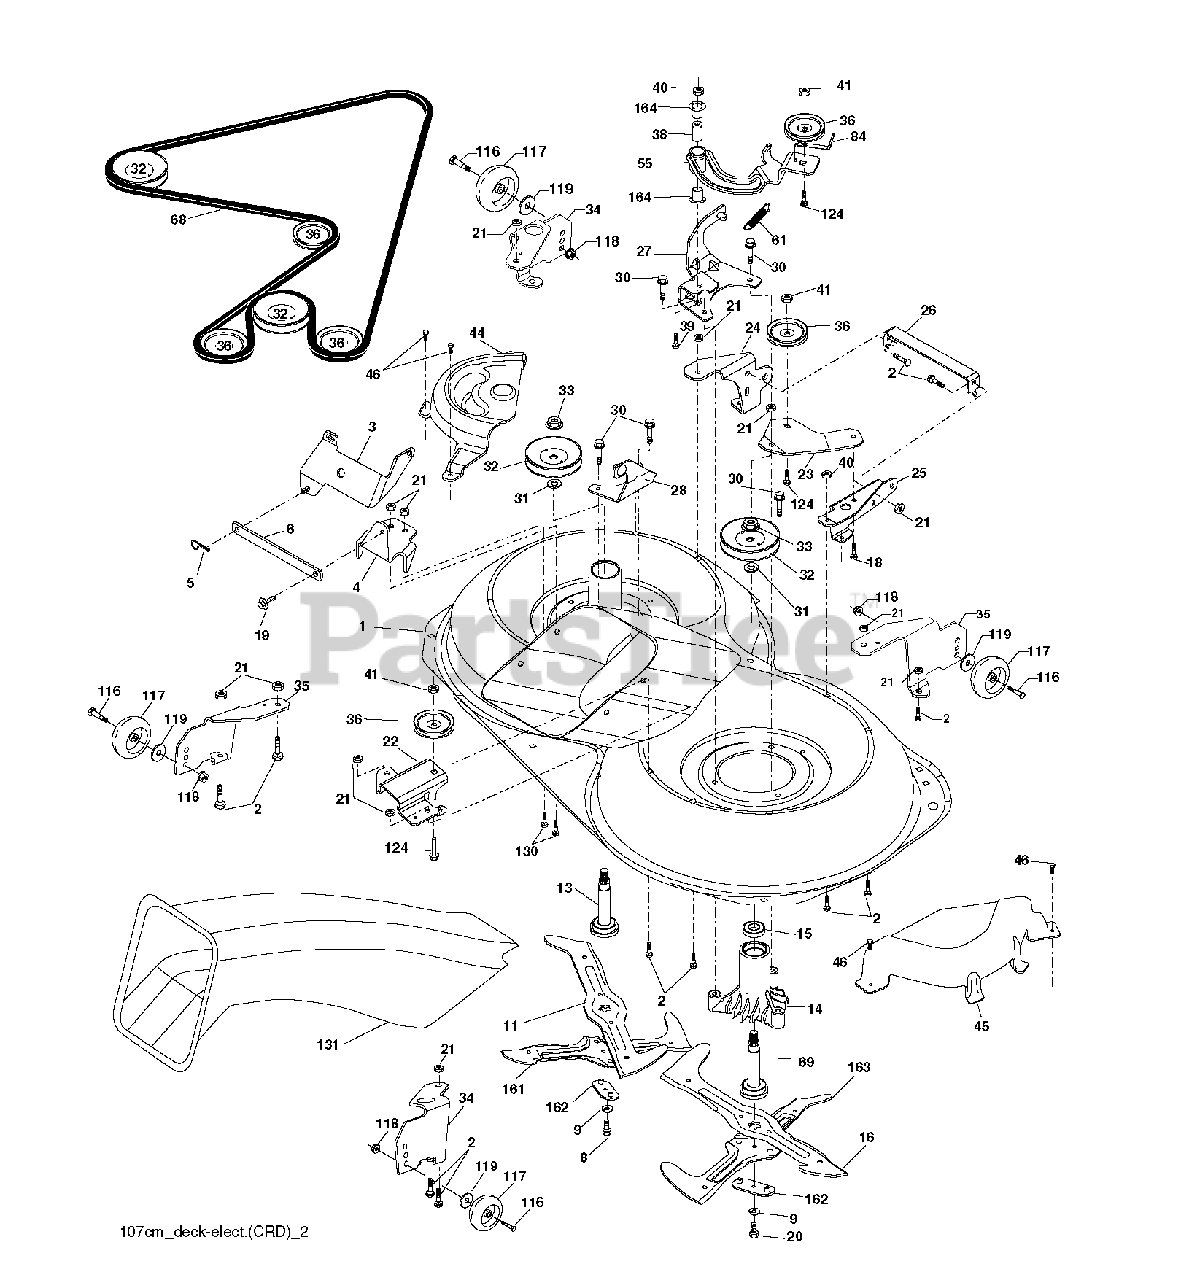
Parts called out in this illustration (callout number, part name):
2	BOLT
3	BRACKET
5	RETAINER-SPRNG RB
6	BAR SWAY
9	LOCKWASHER
11	BLADE.3N1.LH.CRD
13	SHAFT ASM VENT
14	HSG MANDREL
16	BLADE.3N1.RH.CRD
19	BOLT SHD 5/16-18
21	LOCKNUT
22	BRACKET
23	BRACKET
27	BRACKET
30	SCREW, WASHER HEAD
31	WASHER.SPACER.MANDREL
33	NUT.FLANGE.LOCK.TOP
36	PULLEY.IDLER.4.25
40	LOCKNUT
41	NUT LOCK FLG 3/8-16 UNC
45	MANDREL COVER
46	SCREW.1/4-20X5/8
55	ARM IDLER
68	HEX-BELT 107 MOWER
69	SHAFT.ASM.W/LWR.BRG.RH.THREAD
84	KEEPER, BELT IDLER
116	BOLT.SHOULDER.3/8-16X3-5/8
117	WHEEL. GUAGE RALLY
118	NUT LOCK FLG 3/8-16 UNC
124	BOLT.3/8-16X1.50
131	CHUTE BAGGER
164	BRNG T
